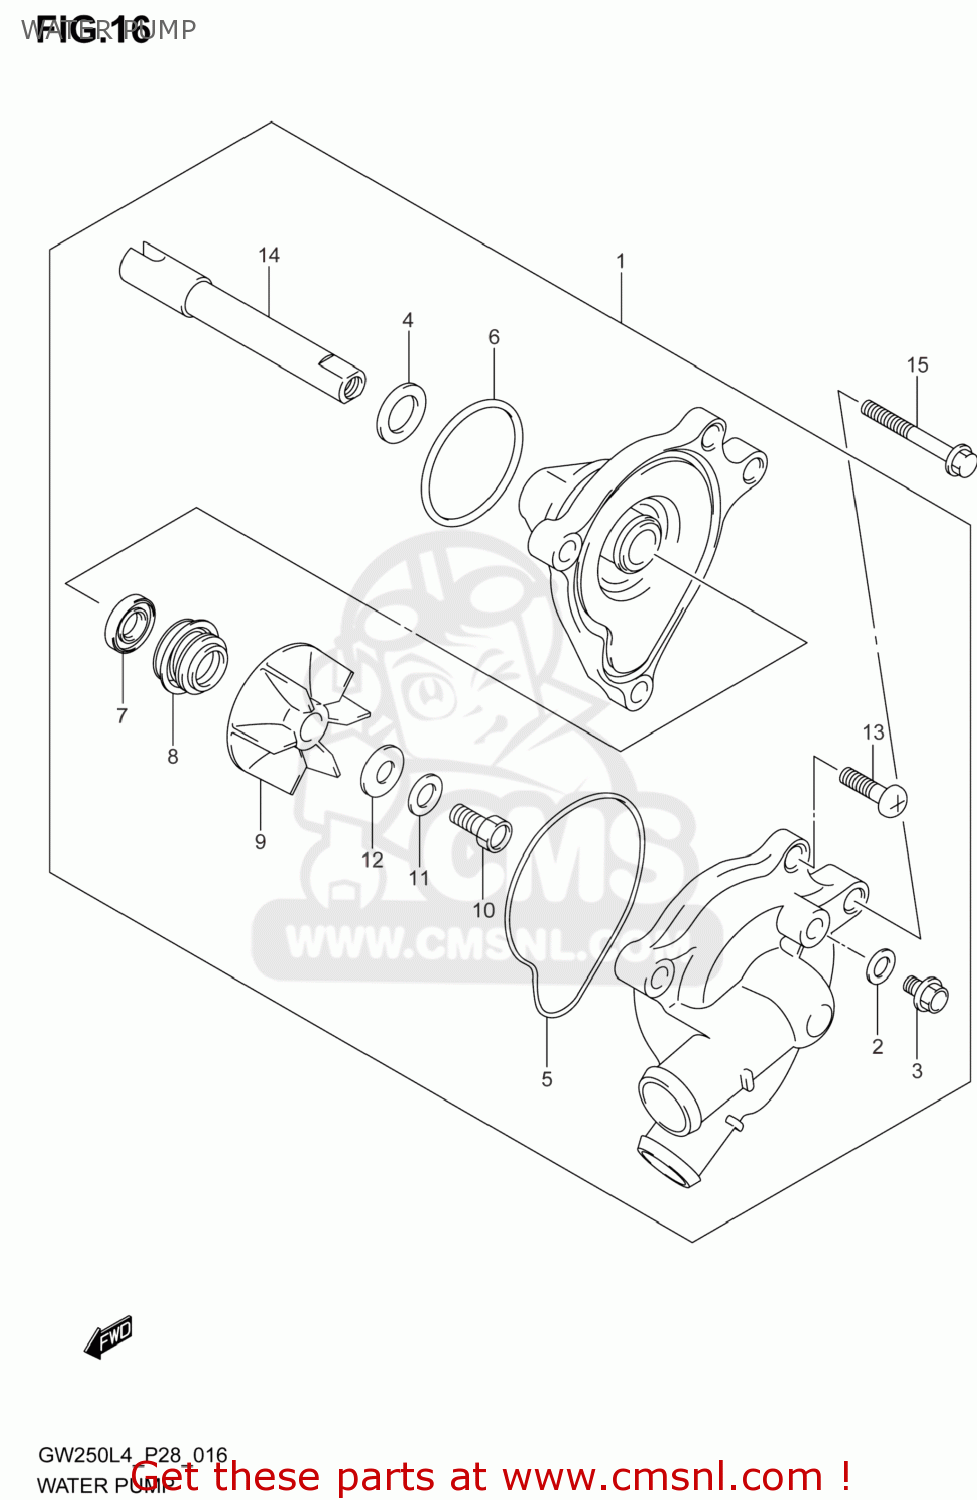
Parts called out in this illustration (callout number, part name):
1	PUMP ASSY,WATER
2	WASHER
3	BOLT
4	WASHER
5	O RING,WATER PUMP CASE
6	O RING,WATER PUMP HOLDER
7	SEAL,OIL
8	SEAL,MECHANICAL
9	IMPELLER,WATER PUMP
10	BOLT(6X13)
11	WASHER
12	GASKET(6X15X2.2) (NAS)
13	SCREW
14	SHAFT
15	BOLT
